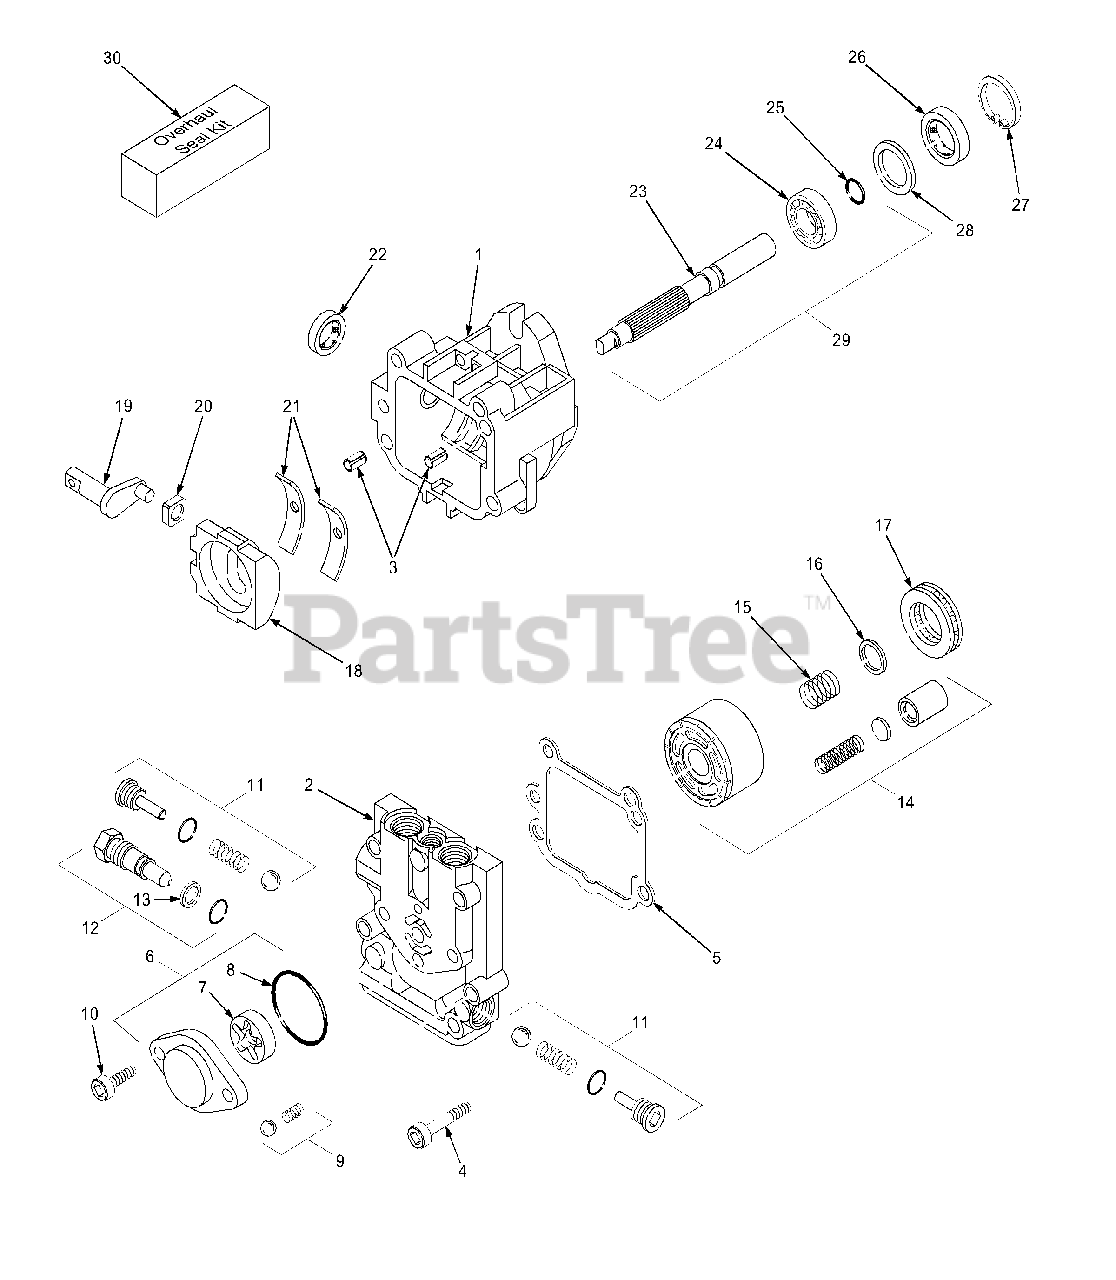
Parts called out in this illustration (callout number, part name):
1	Housing Kit
2	End Cap
3	Straight Headless Pin
4	Socket Head Screw
5	End Cap Gasket
6	Charge Pump Kit
7	Gerotor Assembly
9	Charge Relief Valve Kit
10	Socket Head Screw
11	Check Valve Kit
12	Bypass Valve Kit
13	Backup Ring
14	Cylinder Block Kit
15	Block Spring
16	Block Thrust Washer
17	Roller Thrust Bearing
18	Swash Plate
19	Trunnion Arm
20	Guide Slot
21	Cradle Bearing
23	Pump Shaft
24	Ball Bearing
25	Retaining Ring
27	Retaining Ring
29	Shaft Kit
30	Overhaul Seal Kit
